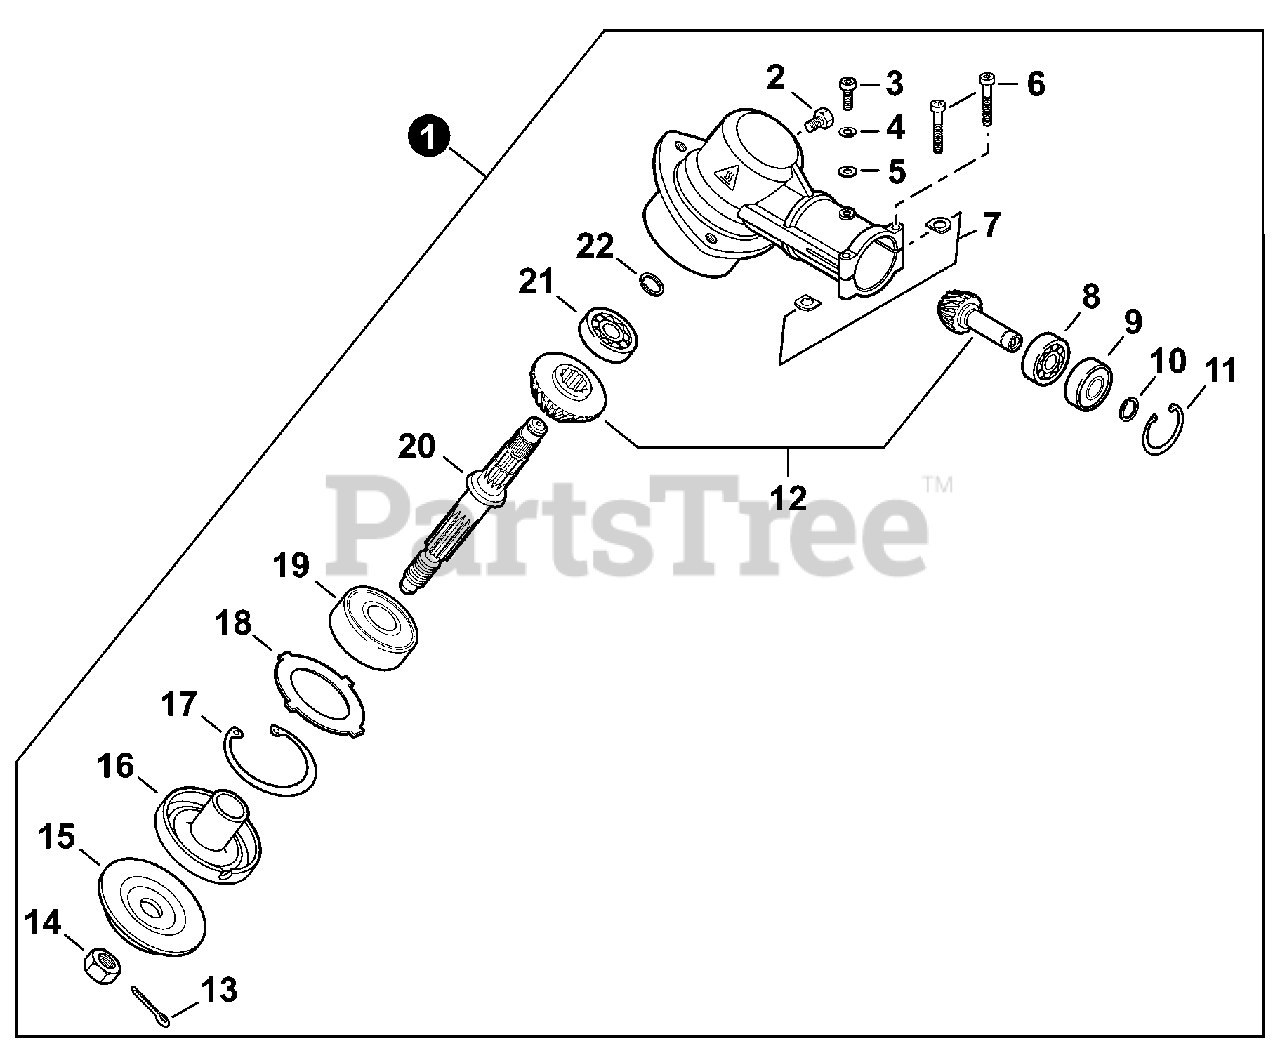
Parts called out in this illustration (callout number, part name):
1	GEAR CASE ASSY
2	BOLT M8×1.25
3	BOLT, TORX 5×10
4	WASHER, SPRING 5
5	WASHER, FLAT 5.5×10×0.8
6	BOLT 5×35
7	D-WASHER
8	BEARING, BALL 6900
9	BEARING, BALL 6900-Z
10	RING, SNAP Ø10
11	RING, SNAP Ø22
12	GEAR SET
13	PIN, COTTER 2×22
15	PLATE, ADAPTOR - LOWER
16	PLATE, ADAPTOR - UPPER
17	RING, SNAP Ø32
19	BEARING, BALL 6201
20	SHAFT, GEAR
21	BEARING, BALL 609
22	RING, SNAP Ø12
